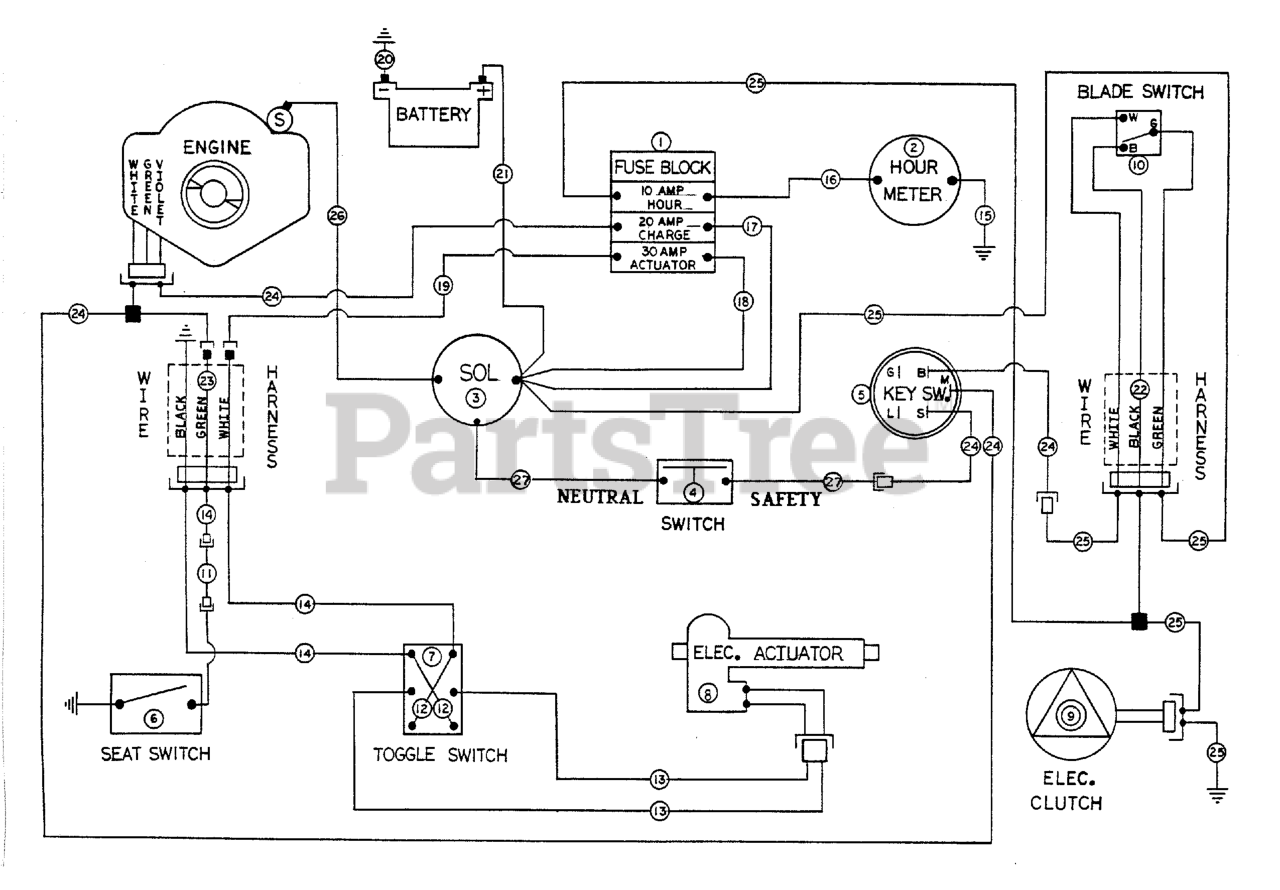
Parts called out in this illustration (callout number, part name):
1	Fuse Block
1	10 Amp Fuse
1	20 Amp Fuse
1	30 Amp Fuse
2	HOUR METER
3	SOLENOID, Starter
4	Neutral Safety Switch
5	SWITCH, Ignition
6	Seat Switch Assembly
7	Toggle Switch
8	Electric Actuator
9	CLUTCH, Electric, 1" Shaft
10	Toggle Switch
11	Green Alpha Cable to Seat Switch
12	Red Corner to Corner Toggle Switch
13	Toggle Switch to Actuator Harness
14	Toggle Switch to Alpha Cable Hanress
15	Blue (-) Hour Meter to Ground
16	Blue Fuse Block to Hour Meter (+)
17	Red Fuse Block to Solenoid
18	White Fuse Block to Solenoid
19	White Alpha Cable to Fuse Block
20	Negative Battery Cable
21	Positive Battery Cable
22	Alpha Cable - Electric Clutch
23	Alpha Cable - Electric Actuator
24	Key Switch / Charge Harness
25	Electric Clutch / Alpha Cable Harness
26	Solenoid to Starter
27	Neutral Safety Switch Wiring Harness
